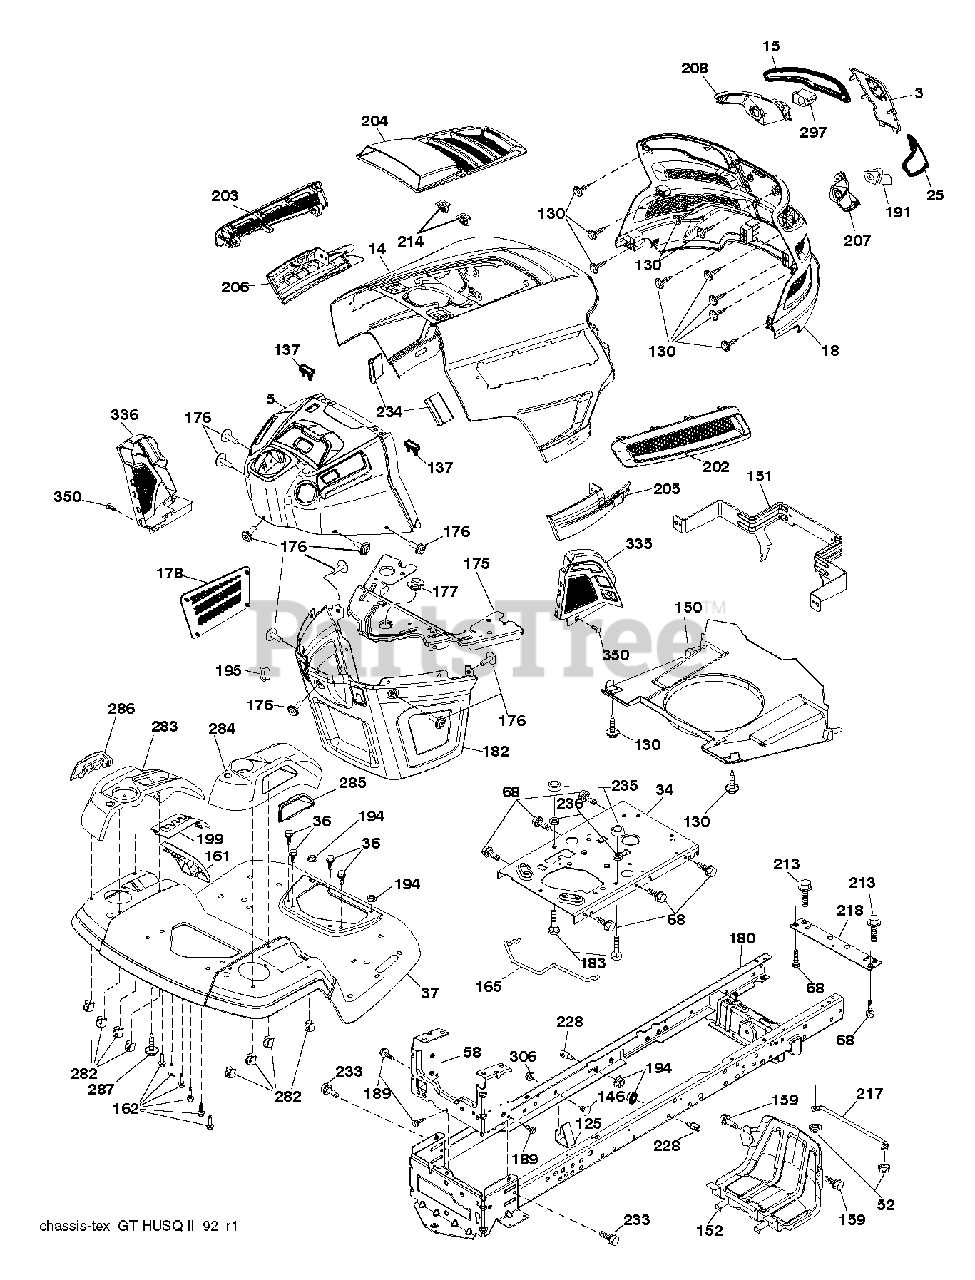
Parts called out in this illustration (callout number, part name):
3	APPLIQUE.SUBASM.GT.HUSQ.II
5	DASH.UPP.GT2.SM.PTO.MC.HR.GREY
14	HOOD.ASM.HUSQVARNA.GT.TEX.ORAN
15	LENS.HEADLIGHT.LH.GTII.2011
18	GRILLE.SUBSTRATE.2011.
25	LENS.HEADLIGHT.RH.GTII.2011
34	PLATE.ENGINE.WELDED.CHASSIS
36	SCREW 5/16"
37	FENDER.TLT.FS.W/CPH/FW/RSF.668
52	LOCKNUT
58	DRAWBAR UPPER 2PC SMALL FENDER
68	SCREW LT
125	CLIP.FUEL.LINE
130	SCREW.#10 X 0.750.BOS
137	BUMPER DASH
146	BOLT.RDHD.SHT.SQNK.3/8-16X5/8
150	AIR.DUCT.GTV.BLACK
151	BRACKET.PIVOT.HOOD.GT.HUSQ.II
152	SHIELD.BROWNING.PNT.GT.V2
159	SCREW, 3/8-16X3/4
161	WINDOW.FUEL.LT.HUSQ.TEX.498
162	SCREW.HI-LO.CONSOLE
165	SUPPORT.TANK.REAR.W/TEX
175	PLATE.CROSSMEMBER.HUSQ
176	SCREW.#10-24X5/8.RN.QU
177	BUSHING, STEERING
178	CARGO.ASM.NET.TXGT.W/C
180	CHASS.WLDMNT.TL.12GA/2P.48/54
182	DASH.LOWER.COMMON.12V.ADAPTOR
183	BOLT.5/16-18X1-1/4 FULL THD
189	SCREW
191	INSERT.REFLECTIVE.RH.HUSQ.GTII
194	NUT LOCK HEX FLANGE 5/16-18
195	PLUG.HOLE.DASH.LOWER.12V.BLK
199	PLATE.DECK.LIFT.HUSQ.LT
202	VENT.SIDE.RH.GT.HUSQ.II.
203	VENT.SIDE.LH.GT.HUSQ.II.498
204	VENT.TOP.HUSQ.GT2
205	SIDE.TRIM.RH.GT.HUSQ.II
206	SIDE.TRIM.LH.GT.HUSQ.II.GRAY
207	BEZEL LIGHT.RH.GT.II.MYLAR
208	BEZEL LIGHT.LH.GT.II.MYLAR
213	BOLT
214	CLIP.RETAINER.TINNER.
217	ROD.PIVOT.HOOD
218	X-PIECE.HOOD.STOP.NON/
228	STUD.FASTNER.W/ANTI-ROTATE
233	BOLT.SHOULDER
234	BUMPER.HOOD.TEX.HUSQVARNA
235	SPACER FENDER
236	NUT.CENTERLOCK.5/16-
282	CLIP.RETAINER.CONSOLE.LT.HUSQ
283	CONSOLE.DECK.LIFT.R.SDFL.HUSQ
284	CONCOLE.CNTRL.PDL.HUSQ.LT.498
285	CONSOLE INSERT RH
286	CONSOLE.INSRT.LH.HUSQ.LT.BLACK
287	SCREW 1/4X20
297	INSERT.REFLECTIVE.LH.HUSQ.GTII
306	NUT LOCK FLG 3/8-16 UNC
335	COVER.LOWER.DASH.RH.BLACK
336	COVER-LH.LOWER.DASH.GT2.BLACK
350	CLIP.X-MAS.TREE
